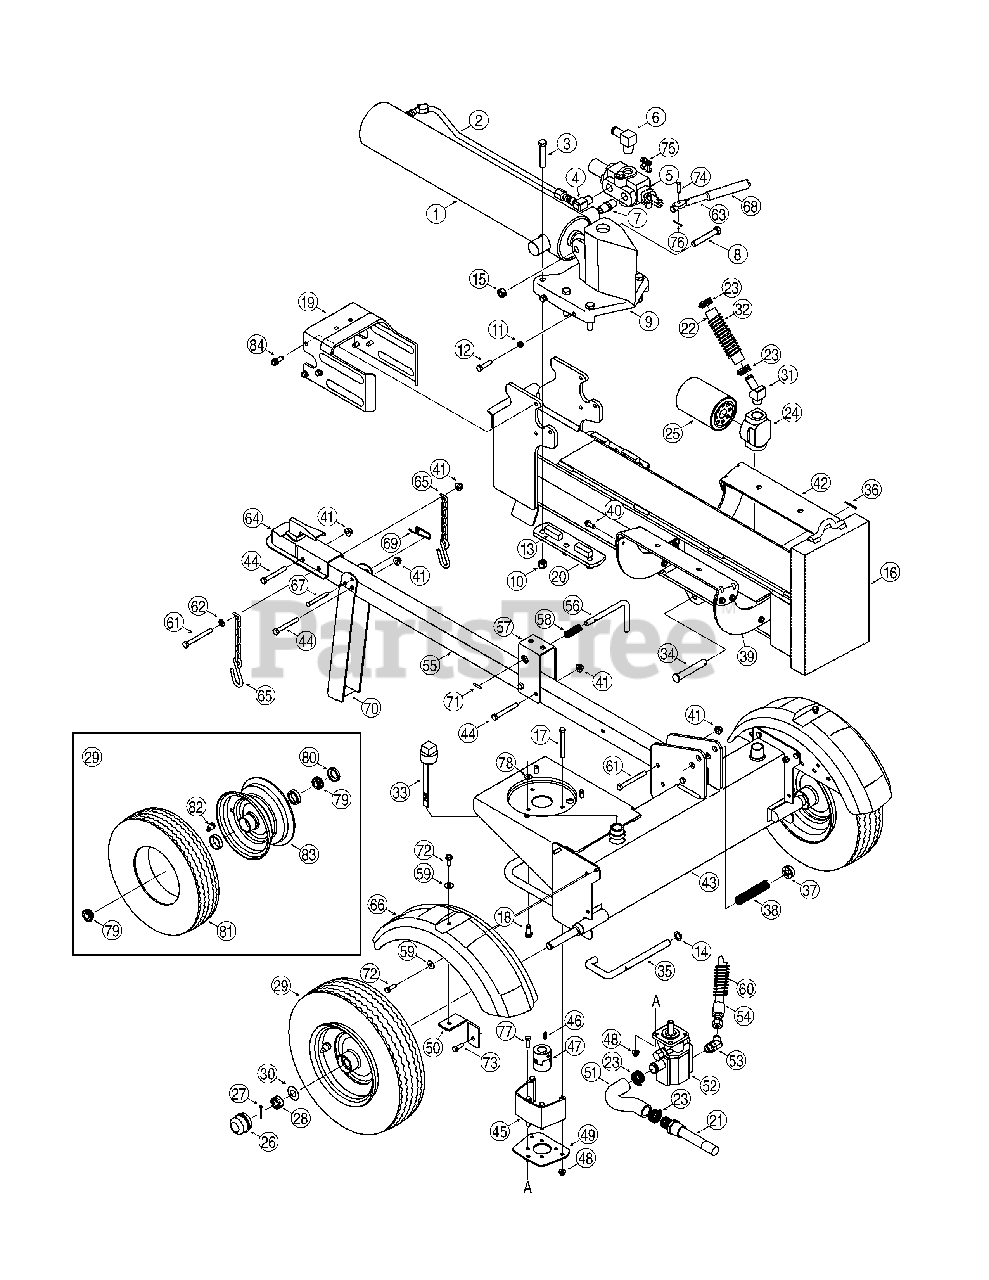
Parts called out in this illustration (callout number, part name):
1	Hydraulic Cylinder
2	Hydraulic Tube
3	Hex Cap Screw 1/2-20 x 2.75
4	90 Degree Solid Adapter
5	Control Valve
6	Return Elbow
7	Nipple Pipe 1/2-14
8	Hex Cap Screw 1/2-13 x 3.25
9	Wedge Assembly
10	Hex Lock Nut, 1/2-20
11	Hex Jam Nut 3/8-24
12	Hex Cap Screw 3/8-24 x 1.5
14	Flat Washer.635 x.93 x.06
15	Hex Lock Nut 1/2-13
16	Beam Assembly
17	Hex Screw, 5/16-18 x 3.25
18	Hex Washer Screw 3/8-16 x 1.250
19	Dislodger Bracket
20	Back Plate
21	Inlet Filter
22	Return Hose 3/4" ID x 44" Lg.
23	Hose Clamp 5/8"
24	Filter Housing
25	Oil Filter
26	Hub Cap
27	Cotter Pin
28	Slotted Nut 3/4-16
29	Wheel Assembly
30	Flat Washer.760 ID x.500 OD
31	Adapter 3/4-14
32	Hose Guard
33	Vented Dipstick
34	Clevis Pin
35	Lock Rod
36	Cotter Pin
37	Push Cap
38	Compression Spring
39	Log Tray Bracket
40	Hex Washer Screw, 5/16-18 x .750
41	Flange Lock Nut, 3/8-16
43	Frame Assembly
44	Hex Bolt 3/8-16 x 3
45	Coupling Shield
46	Square Key 3/16" x.75
47	Screw, 1/4-20 x .38
47	Coupling, .500
47	Coupling, .875
47	Spider Coupling
48	Flange Lock Nut, 5/16-18
49	Rear Coupling Support Bracket
50	Fender Mounting Bracket
52	Gear Pump
53	45 Degree Elbow Fitting
54	High Pressure Hydraulic Hose
55	Tongue Assembly
56	Latch Rod
58	Compression Spring
59	Flat Washer
60	Hose Guard
61	Hex Cap Screw, 3/8-16 x 3.50
62	Flat Washer,.375 x.738 x.063
63	Hydraulic Valve Control
64	Hitch Coupling Assembly
66	Fender
67	Clevis Pin
69	Spring Pin
70	Jack Stand
71	Spiral Pin
72	TT Screw, 5/16-18 x 0.875"
73	TT Screw, 5/16-18 x 1.00
74	Clevis Pin
75	Valve Handle Link
76	Cotter Pin
77	Hex Screw, 5/16-18 x 1.00
78	Flat Washer, .407 x .812 x .135
79	Roller Bearing
80	Dust Seal
81	Tire, 16 x 4.8 x 8.0
82	Tubeless Air Valve
83	Rim Assembly
84	Hex Washer Screw, 3/8-16 x 1.000
